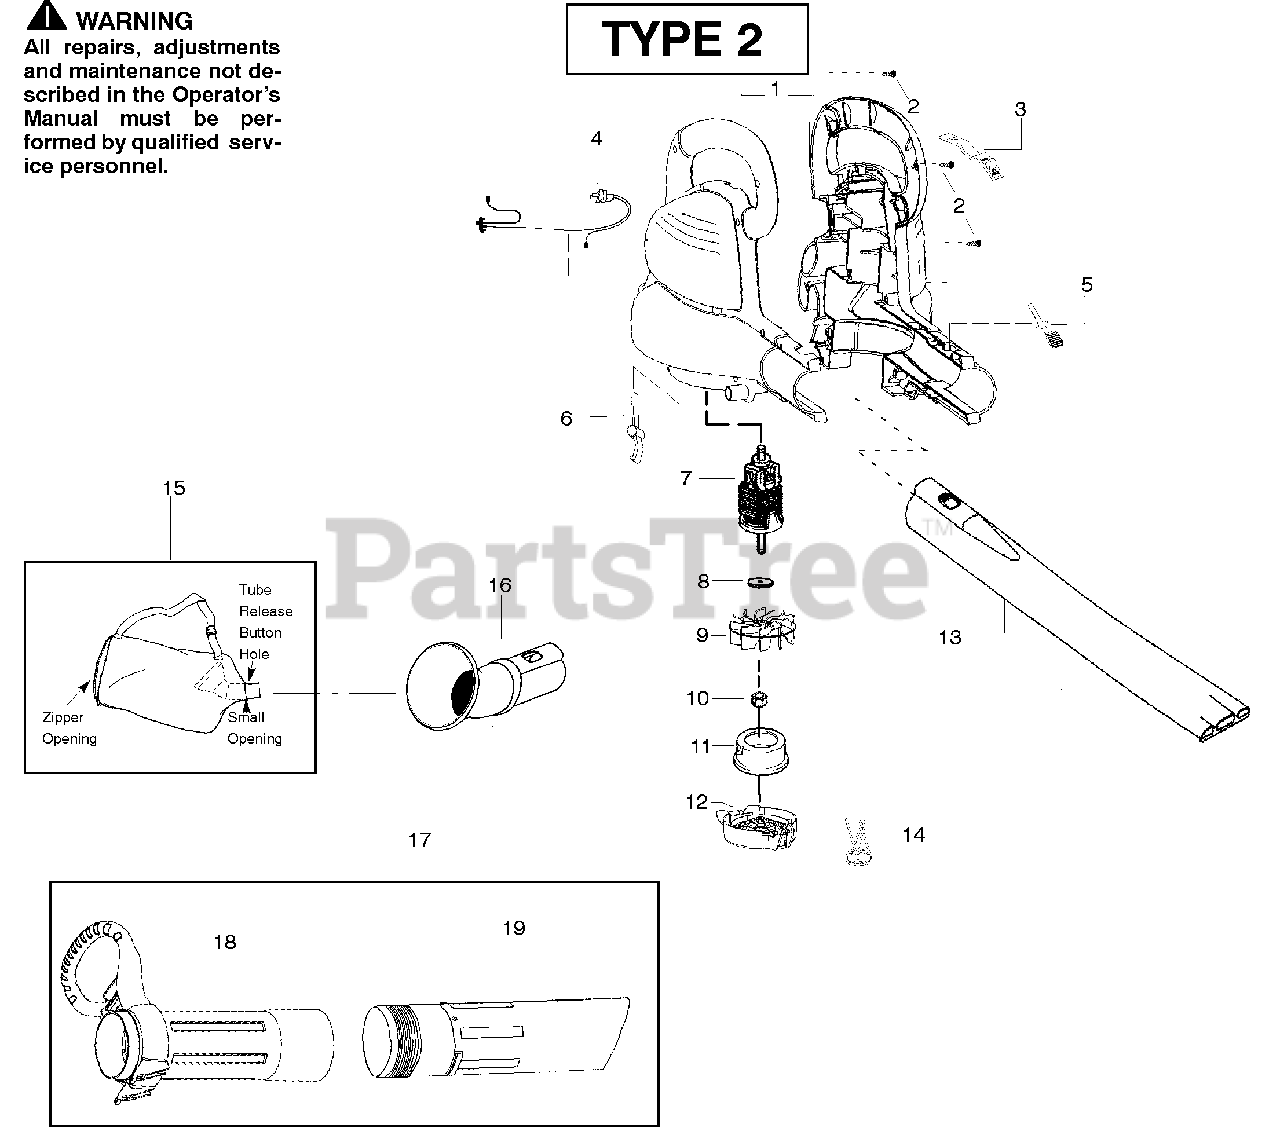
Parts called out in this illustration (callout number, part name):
1	Housing Set
3	Cover - Switch
4	Assy. Wiring Harness
5	Button - Tube Latch
6	Button - Door Latch
7	Assy. Motor
9	Impeller
10	Nut - Impeller
11	Restrictor - Inlet
12	Door - Vacuum Inlet
13	Tube - Blower
14	Spring - Door
15	Assy. - Vac Bag
16	Tube - Elbow
17	Kit-Upper/Lower Tube w/handle
18	Tube - Upper Vac w/handle
19	Tube - Lower Vac
